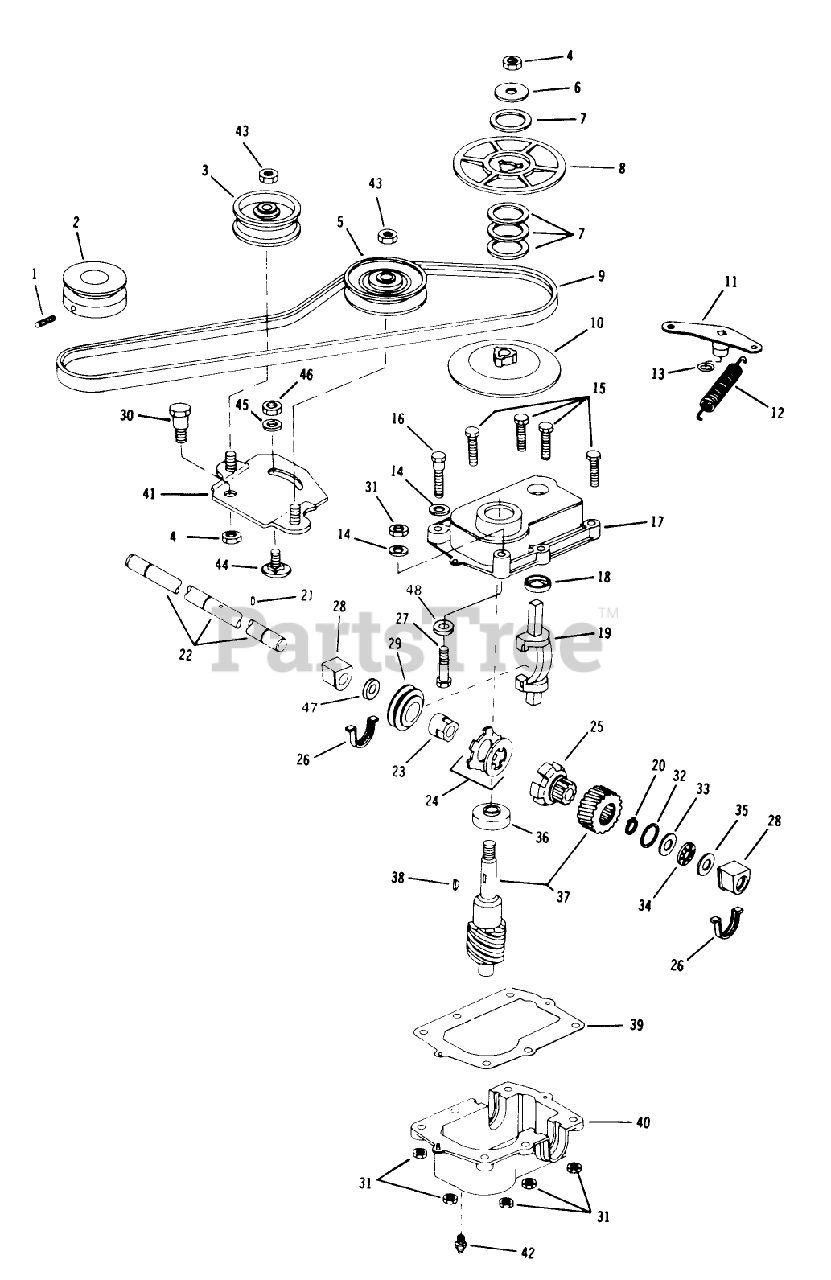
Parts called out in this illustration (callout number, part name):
1	SET SCREW F
2	PULLEY F
3	PULLEY NEWHAM IND *B
4	LOCKNUT
5	IDLER NEW HAM IND
6	WASHER
8	PULLEY UPPER PL
9	V-BELT
10	PULLEY LOWER PL
12	SPRING
13	O-RING
18	GUIDE ELCO
20	RET RING
21	PIN DRIVE LOCK
25	DRIVER BROCKWAY
28	BEARING & SEAL AY (12)
31	LOCKNUT E
33	WASHER-THRUST
35	THRUST WASHER
36	BEARING-BALL
38	KEY GALGER
39	GASKET HOOSIER
42	FITTING LINCOLN
43	NUT-JAM, LOCKING
46	NUT-LOCK F
47	WASHER
